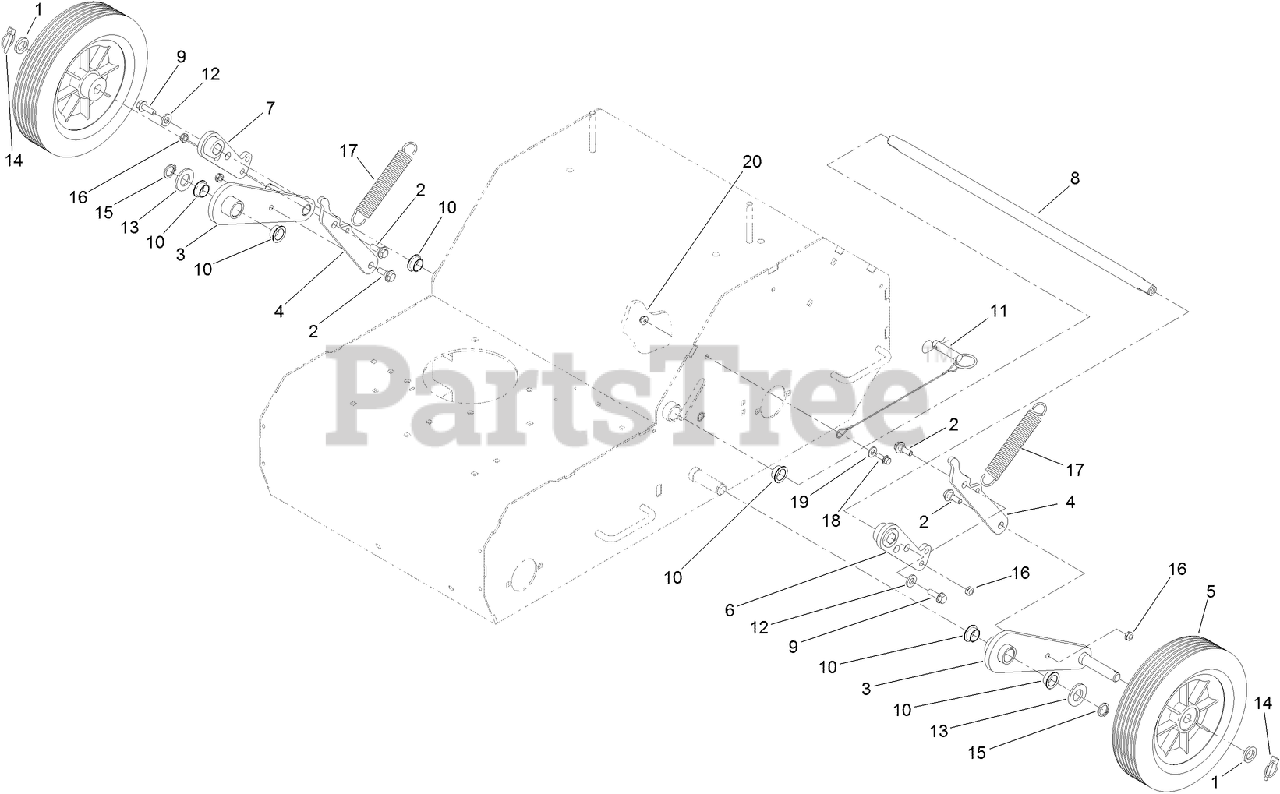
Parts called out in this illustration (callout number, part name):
1	SPACER-BEARING
2	SCREW-SHOULDER
3	ARM-WHEEL
4	LINK-CONNECTING, PINNED
5	WHEEL-TRANSPORT 10"
6	HUB-LIFT, LH
7	HUB-LIFT, RH
8	SHAFT-PIVOT
9	SCREW-HHF
10	BUSHING-BRONZE
11	Hitch Pin ASM
12	WASHER-HARDENED
13	WASHER-FLAT
14	PIN-KLIK
15	RING-RETAINING
16	NUT-LOCK, NI
17	SPRING-EXTENSION
18	SCREW-HHF
19	WASHER-PLAIN
20	NUT-HF
